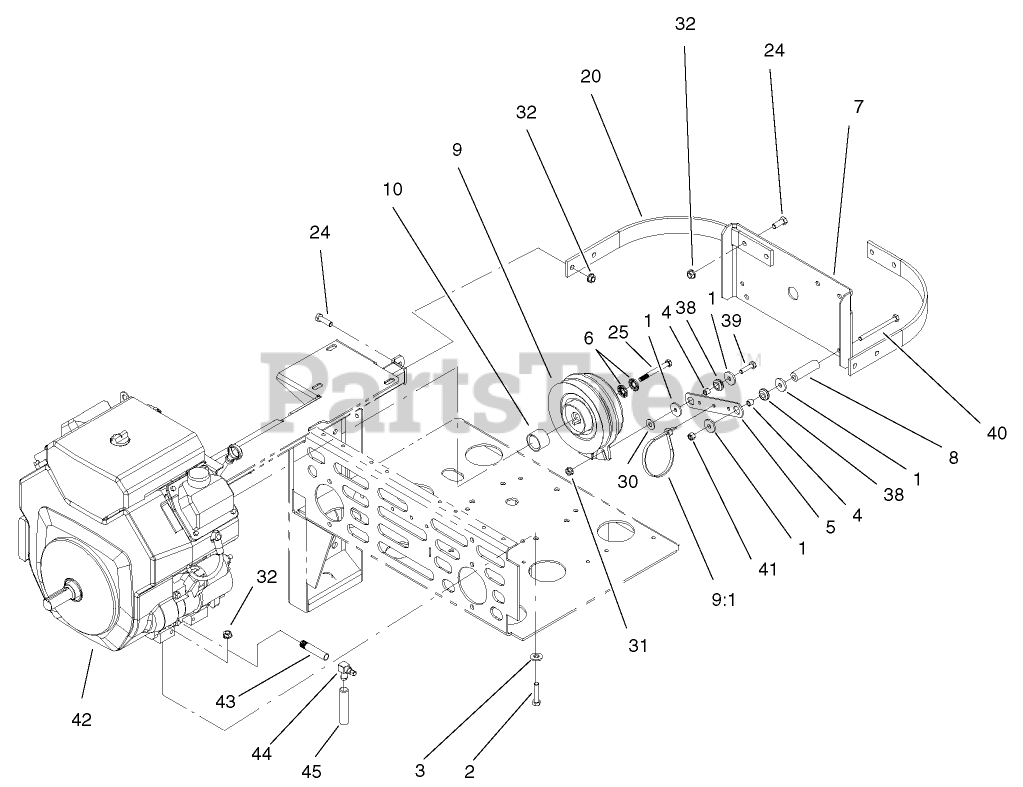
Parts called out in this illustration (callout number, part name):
1	WASHER
2	SCREW-HH
3	WASHER-BELLEVILLE
4	SPACER
5	STRAP-CLUTCH, BRAKE
6	WASHER-SPRING
7	GUARD-CLUTCH
8	SPACER-ANCHOR, CLUTCH
9	Clutch
9:1	TIE-PLASTIC
10	SPACER-CLUTCH
20	BRACKET-GUARD, TOP
24	SCREW-HH
25	SCREW-HH
30	WASHER-FLAT
31	NUT-HF
32	NUT-HHF, WHIZ
38	GROMMET
39	SCREW-HH
40	SCREW-HH
41	NUT-LOCK, NI
43	Adapter
44	Valve-Drain, Oil
45	HOSE-DRAIN, OIL
